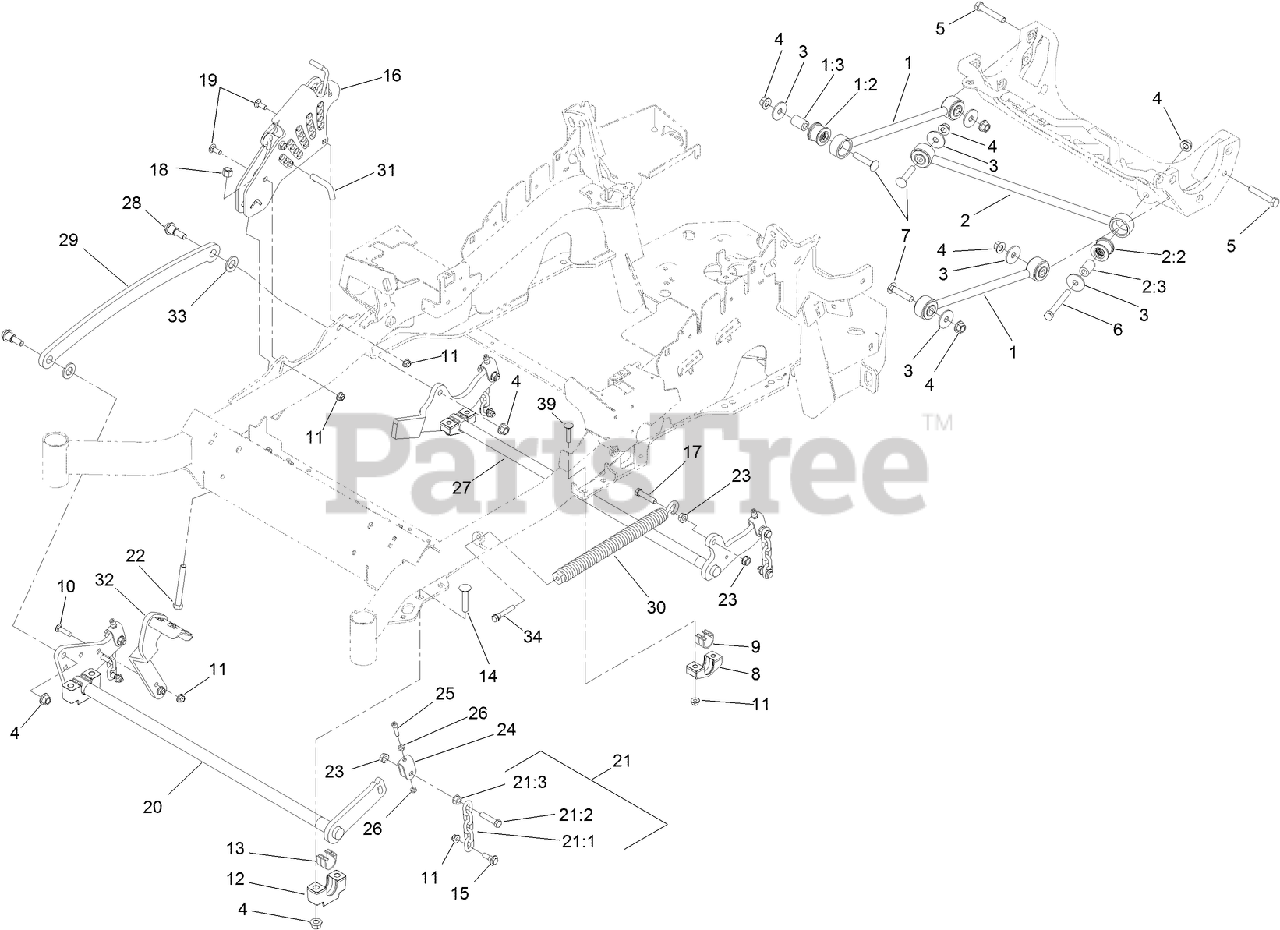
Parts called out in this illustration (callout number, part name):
1	DECK STRUT ASM
1:2	BUSHING-SUSPENSION, RUBBER
1:3	SPACER
2	PANHARD ROD ASM
2:2	BUSHING-SUSPENSION, RUBBER
2:3	SPACER
3	WASHER-THRUST
4	NUT-LOCK
5	SCREW-HH
6	SCREW-HH
7	SCREW-CARR
8	SUPPORT-CROSS SHAFT, REAR BEARING
9	BEARING-CROSS SHAFT, REAR
10	SCREW-CARR
11	NUT-HF, NI
12	SUPPORT-CROSS SHAFT, BEARING
13	BEARING-CROSS SHAFT, FRONT
14	BOLT-CARR
15	SCREW-SHOULDER, HHF
16	HOC ASM
17	SCREW-HH
18	NUT-LOCK, NI
19	BOLT-CARR
20	CROSS SHAFT-FRONT
21	DECK LIFT CHAIN ASM
21:1	CHAIN-LIFT, DECK
21:2	SCREW-HH
21:3	NUT-HF
22	BOLT-TAP
23	NUT-HF
24	YOKE-ADJUST, DECK
25	SCREW-HH
26	NUT-JAM
27	LIFT-DECK, REAR
28	SCREW-SHOULDER, HHF
29	LINK-LIFT, DECK
30	SPRING-EXTENSION
31	PIN-HOC
32	LEVER-FOOT
33	WASHER-FLAT
34	BOLT-SHOULDER
39	SCREW-CARR
